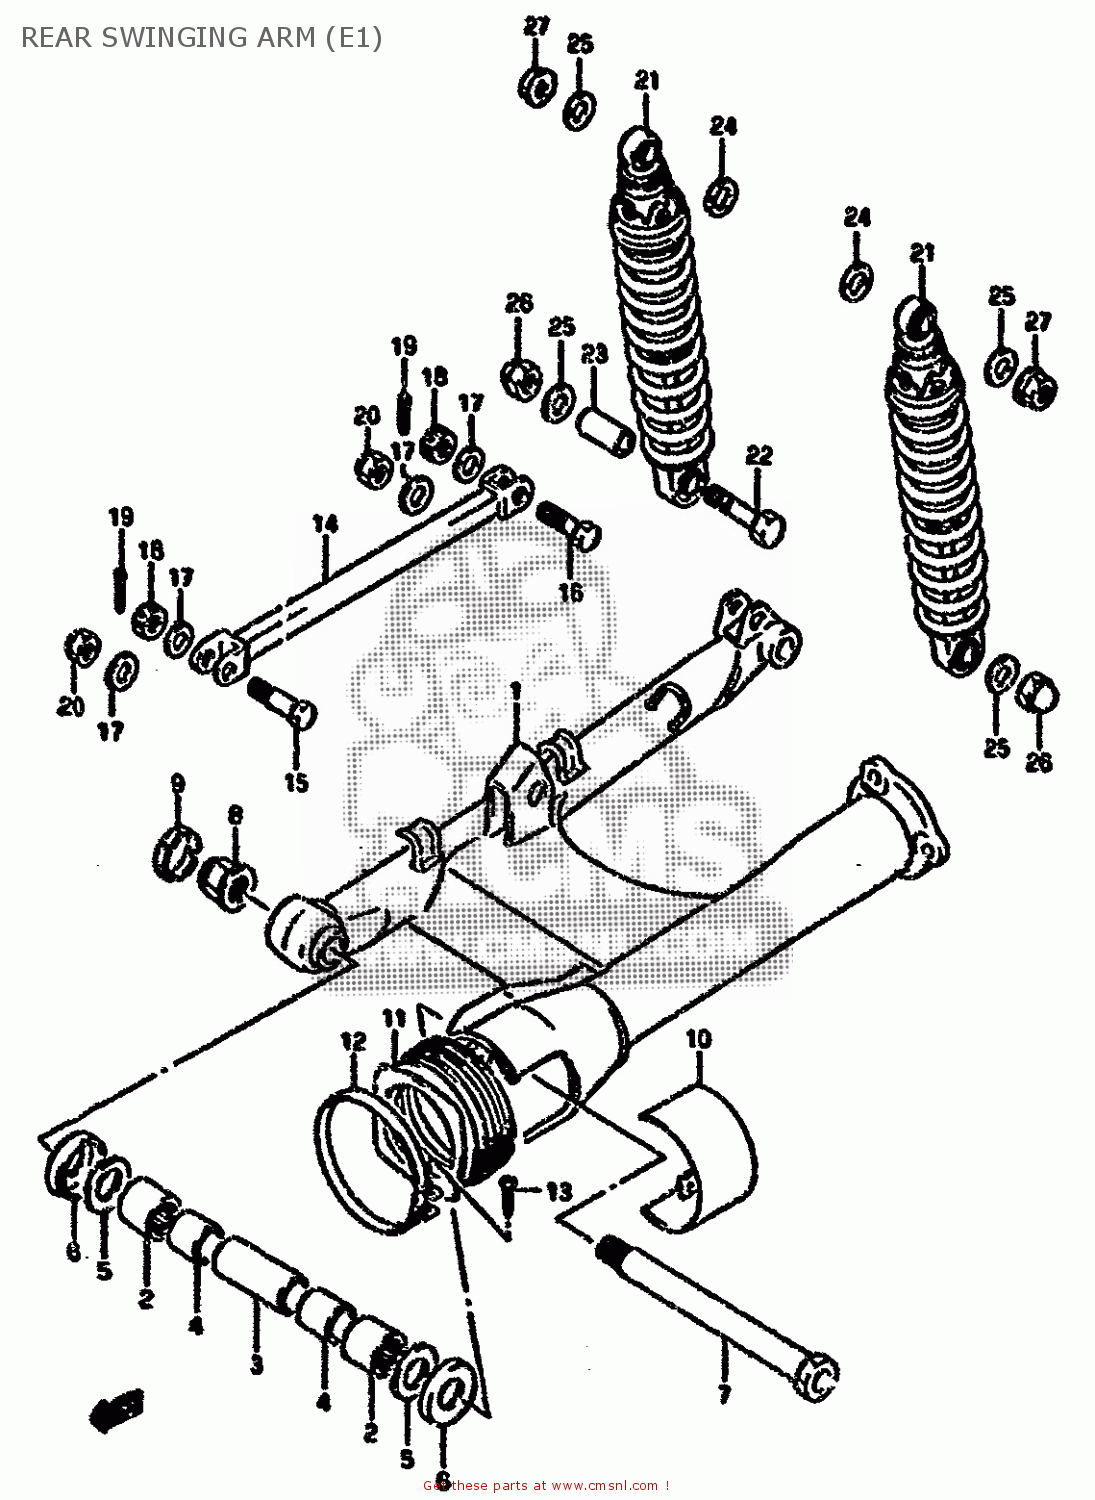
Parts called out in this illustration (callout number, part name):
1	SWING ARM,REAR
2	BEARING(25X33X30)
3	SPACER,REAR SWING ARM PIVOT
4	SPACER,RR SWGARM PIVOT BERRING
5	WASHER
6	COVER,RR SWGARM PIVOT SEAL
7	SHAFT,RR SWINGINGARM PIVOT
8	NUT ,18MM
9	CAP,RR SWINGING ARM PIVOT
10	COVER,SWGARM PIVOT,L
11	BOOT,PROPELLER SHAFT
12	CLAMP
13	SCREW 4X25
14	TORQUE LINK,REAR
15	BOLT(10X41)
16	BOLT
17	WASHER
18	NUT
19	PIN 20X20
20	NUT
21	ABSORBER ASSEMBLY,REAR SHOCK
22	BOLT(10X39)
23	SPACER (10.2X14X20.7)
24	WASHER
25	WASHER
26	NUT
27	NUT
